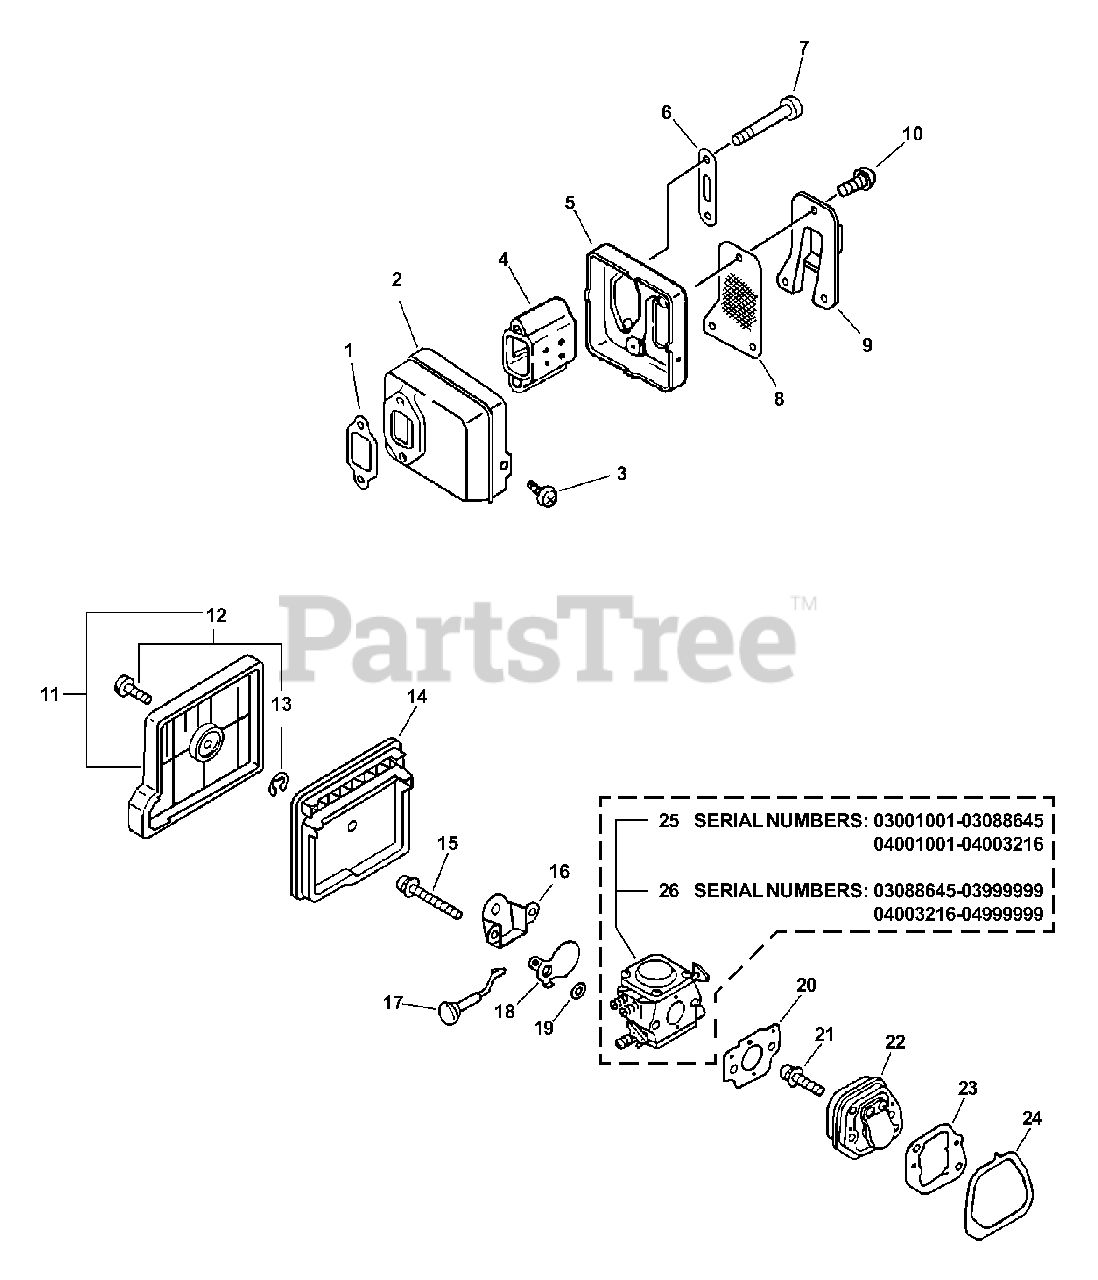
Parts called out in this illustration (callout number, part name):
1	GASKET, EXHAUST
2	GUIDE, EXHAUST
3	SCREW - 4X8
4	BAFFLE, MUFFLER
5	GUIDE, EXHAUST
7	BOLT - FLANGE
8	SCREEN, SPARK ARRESTOR
9	GUIDE, EXHAUST
10	SCREW - 4X8
11	AIR FILTER COVER ASSY
12	THUMBSCREW
13	RING, RETAINING - 4
14	FILTER, AIR
15	SCREW - 5X45
16	PLATE, PREVENT
17	ROD, CHOKE
18	SHUTTER, CHOKE
19	WASHER
20	GASKET, INTAKE
21	SCREW - 5X18
22	INSULATOR KIT
23	GASKET, INTAKE
24	SEAL
25	CARBURETOR WT-589
26	CARBURETOR WT-589
